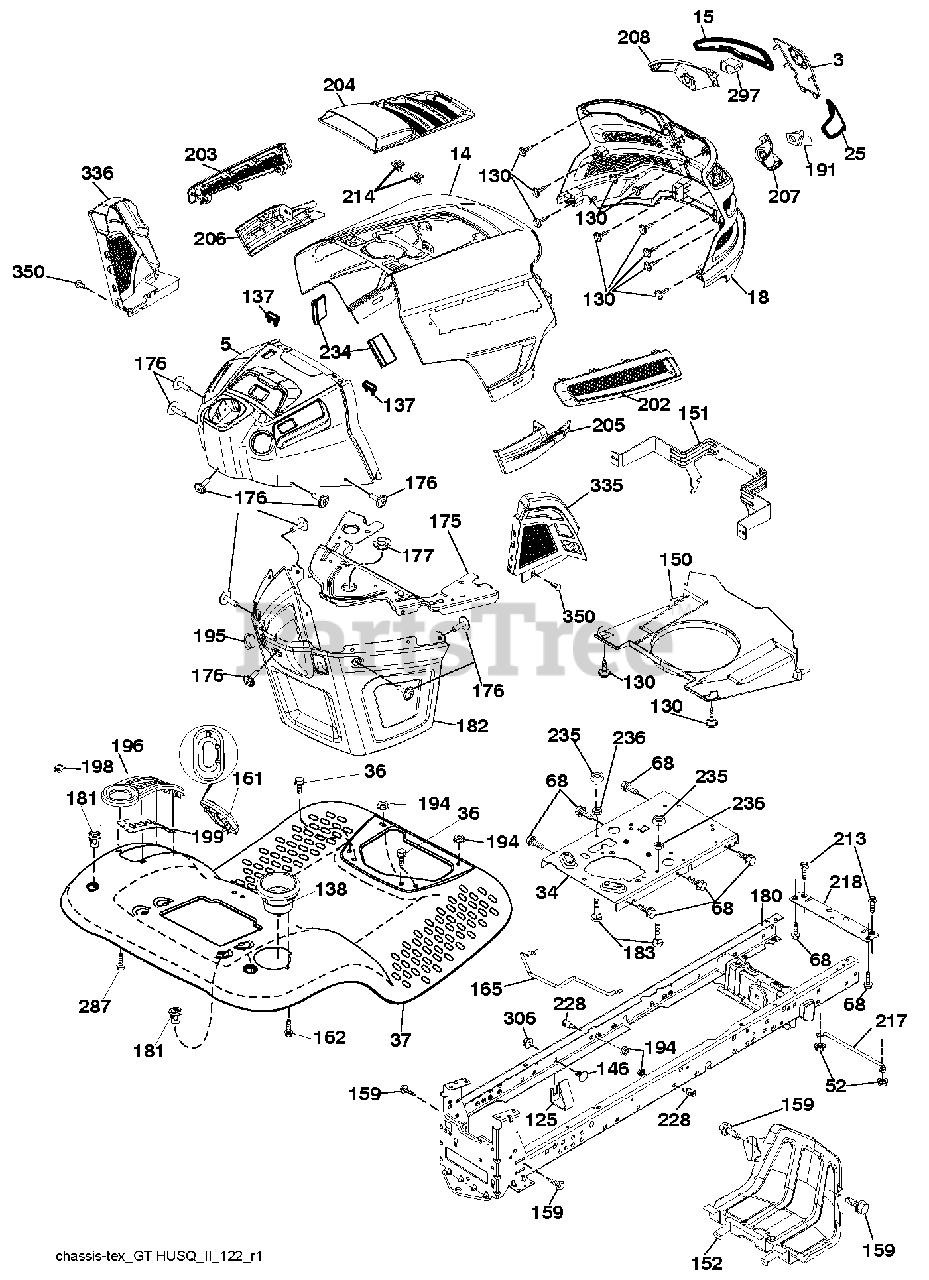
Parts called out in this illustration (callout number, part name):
3	APPLIQUE.SUBASM.GT.HUSQ.II
5	DASH.UPPER.ASSY.GT2.GREY
14	HOOD.ASM.HUSQVARNA.GT.TEX.ORAN
15	LENS.HEADLIGHT.LH.GTII.2011
18	GRILLE.SUBSTRATE.2011.
25	LENS.HEADLIGHT.RH.GTII.2011
34	PLATE.ENGINE.WELDED.CHASSIS
36	SCREW 5/16"
37	FENDER.ERGO.LT.W/CPH.W/FW.ORNG
52	LOCKNUT
68	SCREW LT
125	CLIP.FUEL.LINE
130	SCREW.#10 X 0.750.BOS
137	BUMPER DASH
138	HOLDER.CUP.LT.GREY
146	BOLT.RDHD.SHT.SQNK.3/8-16X5/8
150	AIR.DUCT.GTV.BLACK
151	BRACKET.PIVOT.HOOD.GT.HUSQ.II
152	SHIELD.BROWNING.PNT.GT.V2
159	SCREW, 3/8-16X3/4
161	WINDOW.FUEL.LT.HUSQ.TEX.498
162	SCREW.HI-LO.CONSOLE
165	SUPPORT.TANK.REAR.W/TEX
175	PLATE.CROSSMEMBER.HUSQ
176	SCREW.#10-24X5/8.RN.QU
177	BUSHING, STEERING
180	CHASSIS
181	BUSHING.MNT.FEND.CRGO.TEX.49
182	DASH.LOWER.COMMON.12V.ADAPTOR
183	BOLT.5/16-18X1-1/4 FULL THD
191	INSERT.REFLECTIVE.RH.HUSQ.GTII
194	NUT LOCK HEX FLANGE 5/16-18
195	PLUG.HOLE.DASH.LOWER.12V.BLK
196	DECKLFT.CONSOL FULL ASSM GREY
198	INDICATOR.DECK.LIFT.RED
199	PLATE.DECK.LIFT.HUSQ.LT
202	VENT.SIDE.RH.GT.HUSQ.II.
203	VENT.SIDE.LH.GT.HUSQ.II.498
204	VENT.TOP.HUSQ.GT2
205	SIDE.TRIM.RH.GT.HUSQ.II
206	SIDE.TRIM.LH.GT.HUSQ.II.GRAY
207	BEZEL LIGHT.RH.GT.II.MYLAR
208	BEZEL LIGHT.LH.GT.II.MYLAR
213	BOLT
214	CLIP.RETAINER.TINNER.
217	ROD.PIVOT.HOOD
218	X-PIECE.HOOD.STOP.NON/
228	STUD.FASTNER.W/ANTI-ROTATE
234	BUMPER.HOOD.TEX.HUSQVARNA
235	SPACER FENDER
236	NUT.CENTERLOCK.5/16-
287	SCREW 1/4X20
297	INSERT.REFLECTIVE.LH.HUSQ.GTII
306	NUT LOCK FLG 3/8-16 UNC
335	COVER.LOWER.DASH.RH.BLACK
336	COVER-LH.LOWER.DASH.GT2.BLACK
350	CLIP.X-MAS.TREE
